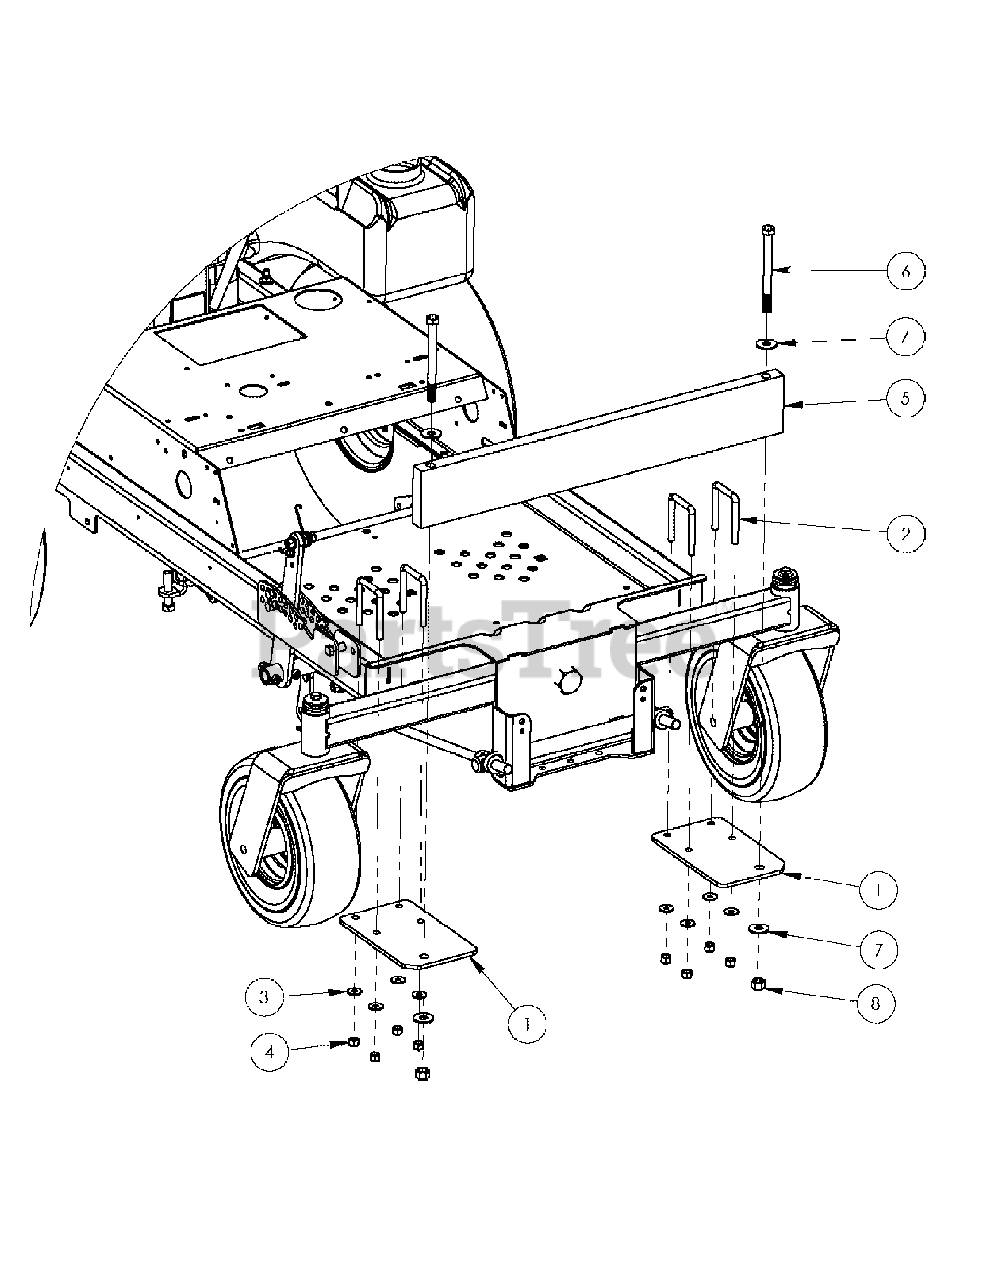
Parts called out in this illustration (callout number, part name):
1	WEIGHT BRACKET
3	FLAT WASHER-5/16"
4	HEX NUT, NYLON INSERT-3/8"-16
5	BAR, WEIGHT-
6	CAP SCREW, 1/2"-13 X 5 1/2" LONG
7	FLAT WASHER-1/2"
8	HEX NUT, NYLON INSERT-1/2"-13
